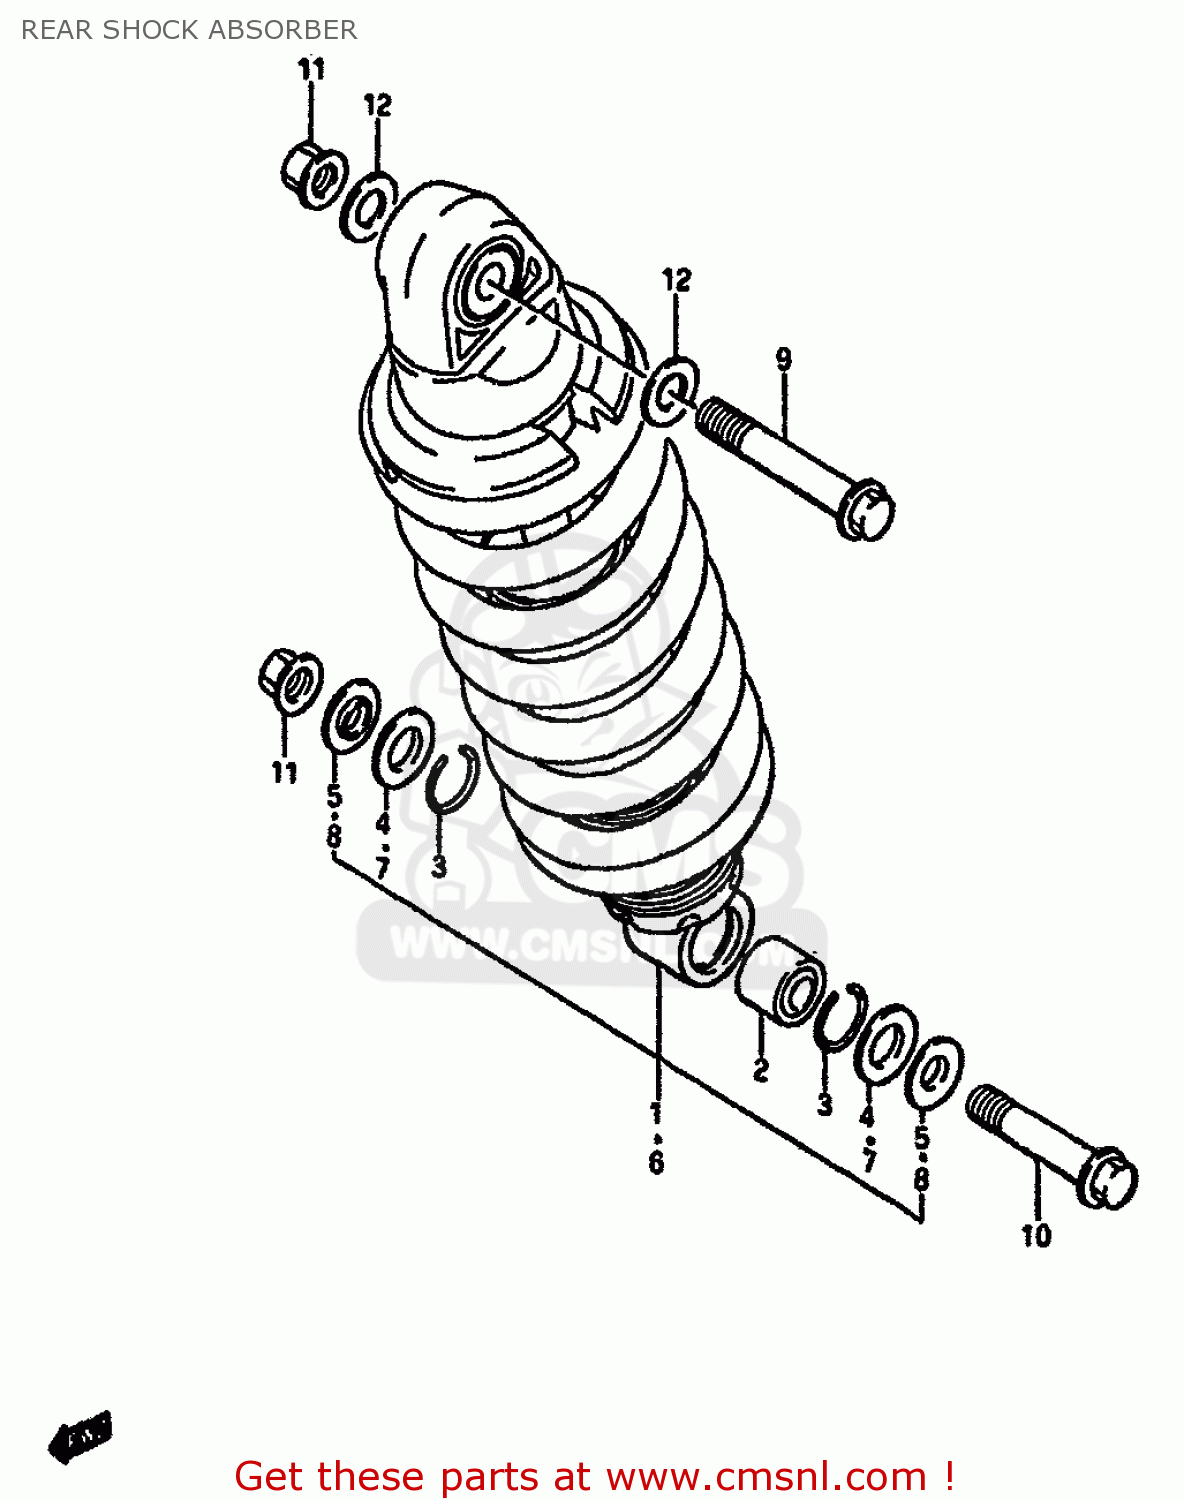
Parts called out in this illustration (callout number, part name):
1	ABSORBER ASSEMBLY,REAR SHOCK
2	BEARING,REAR SHOCK ABSORBER
3	RING
4	SEAL,DUST UPR
5	COLLAR,UPR
6	ABSORBER ASSY,RR SHOCK
7	SEAL DUST
8	COLLAR
9	BOLT
10	BOLT,RR CUSHION ROD UPR
11	NUT
12	WASHER,REAR SHOCK ABSORBER
